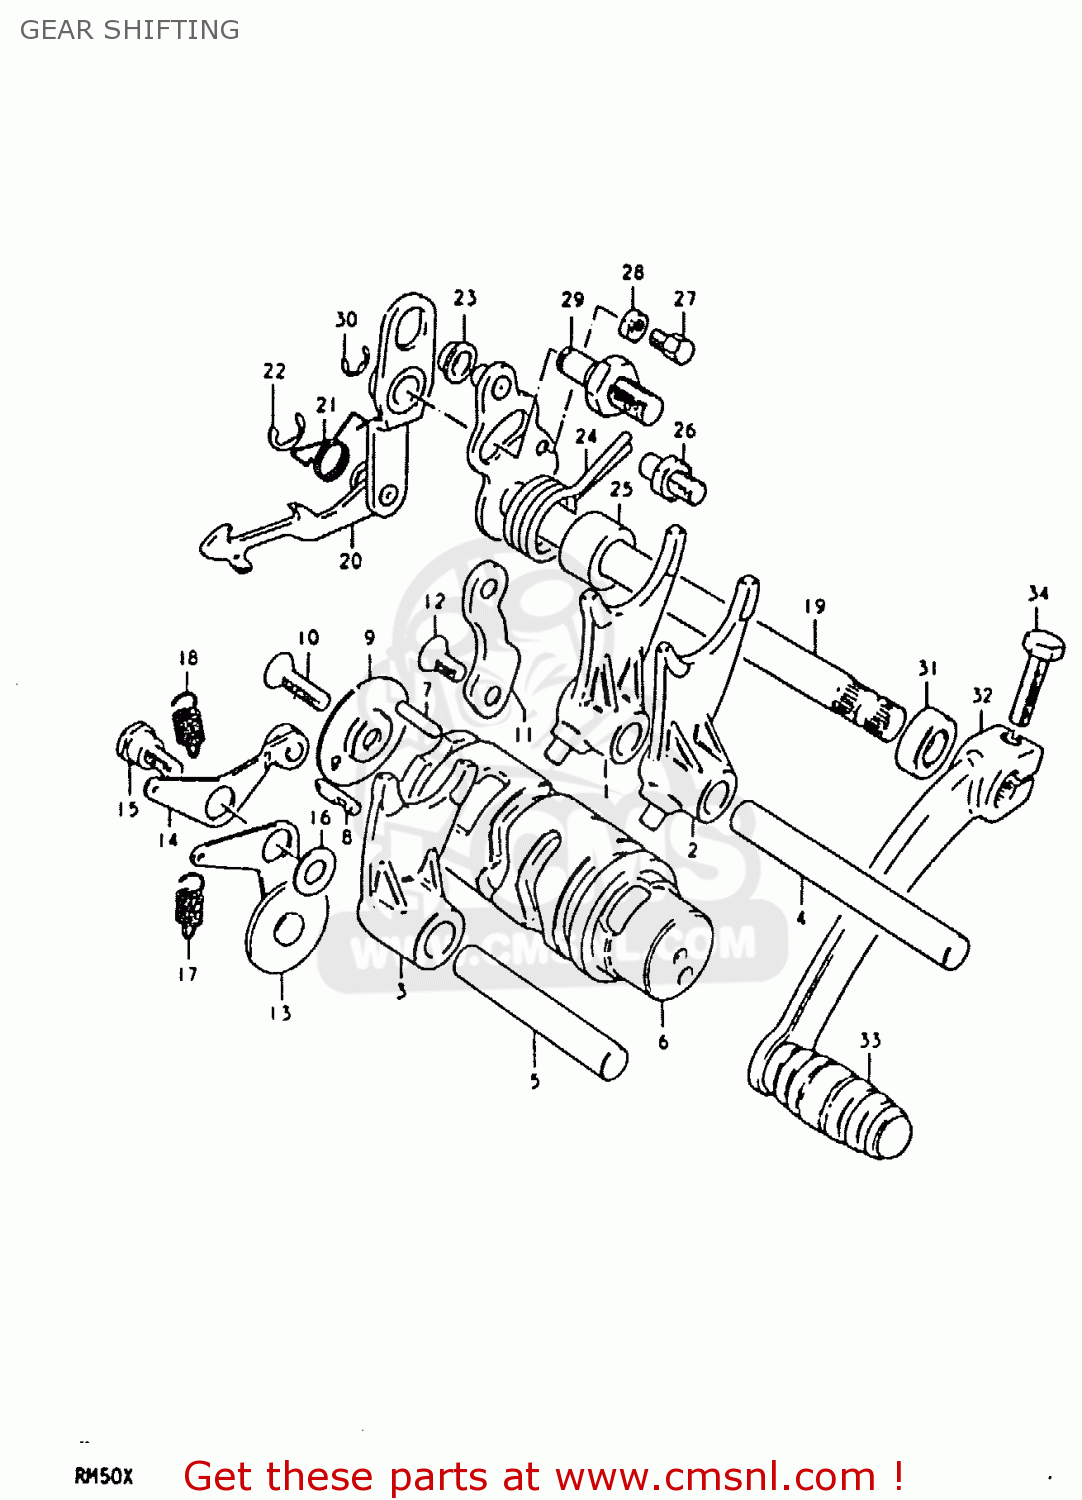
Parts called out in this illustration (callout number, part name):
1	FORK,GEAR SHIFT NO.1
2	FORK,GEAR SHIFT NO.2
3	FORK,GEAR SHIFT NO.3
4	SHAFT,GEAR SHIFT FORK
5	SHAFT,GEAR SHIFT FORK
6	CAM,GEAR SHIFT
7	PIN(4X15.8)
8	PIN
9	RETAINER,GEAR SHIFT CAM DR PIN
10	SCREW
11	GUIDE,GEAR SHIFT CAM
12	SCREW
13	STOPPER,GEAR SHIFT CAM
14	STOPPER,GEAR SHIFT CAM NEUTRAL
15	BOLT(6X18.3)
16	WASHER
17	SPRING
18	SPRING
19	SHAFT,GEAR SHIFT
20	PAWL,GEAR SHIFTING
21	SPRING
22	E RING
23	SPACER(7X10X5)
24	SPRING
25	SPACER(12X20X15.3)
26	STOPPER,GEAR SHIFT CAM
27	BOLT,GEAR SHAFT RETURN SPR SET
28	NUT 6MM
29	STOPPER,GEAR SHIFT CAM
30	E RING 6MM
31	OIL SEAL
32	LEVER, GEAR SHIFTING
33	RUBBER,GEAR SHIFT PEDAL
34	BOLT
